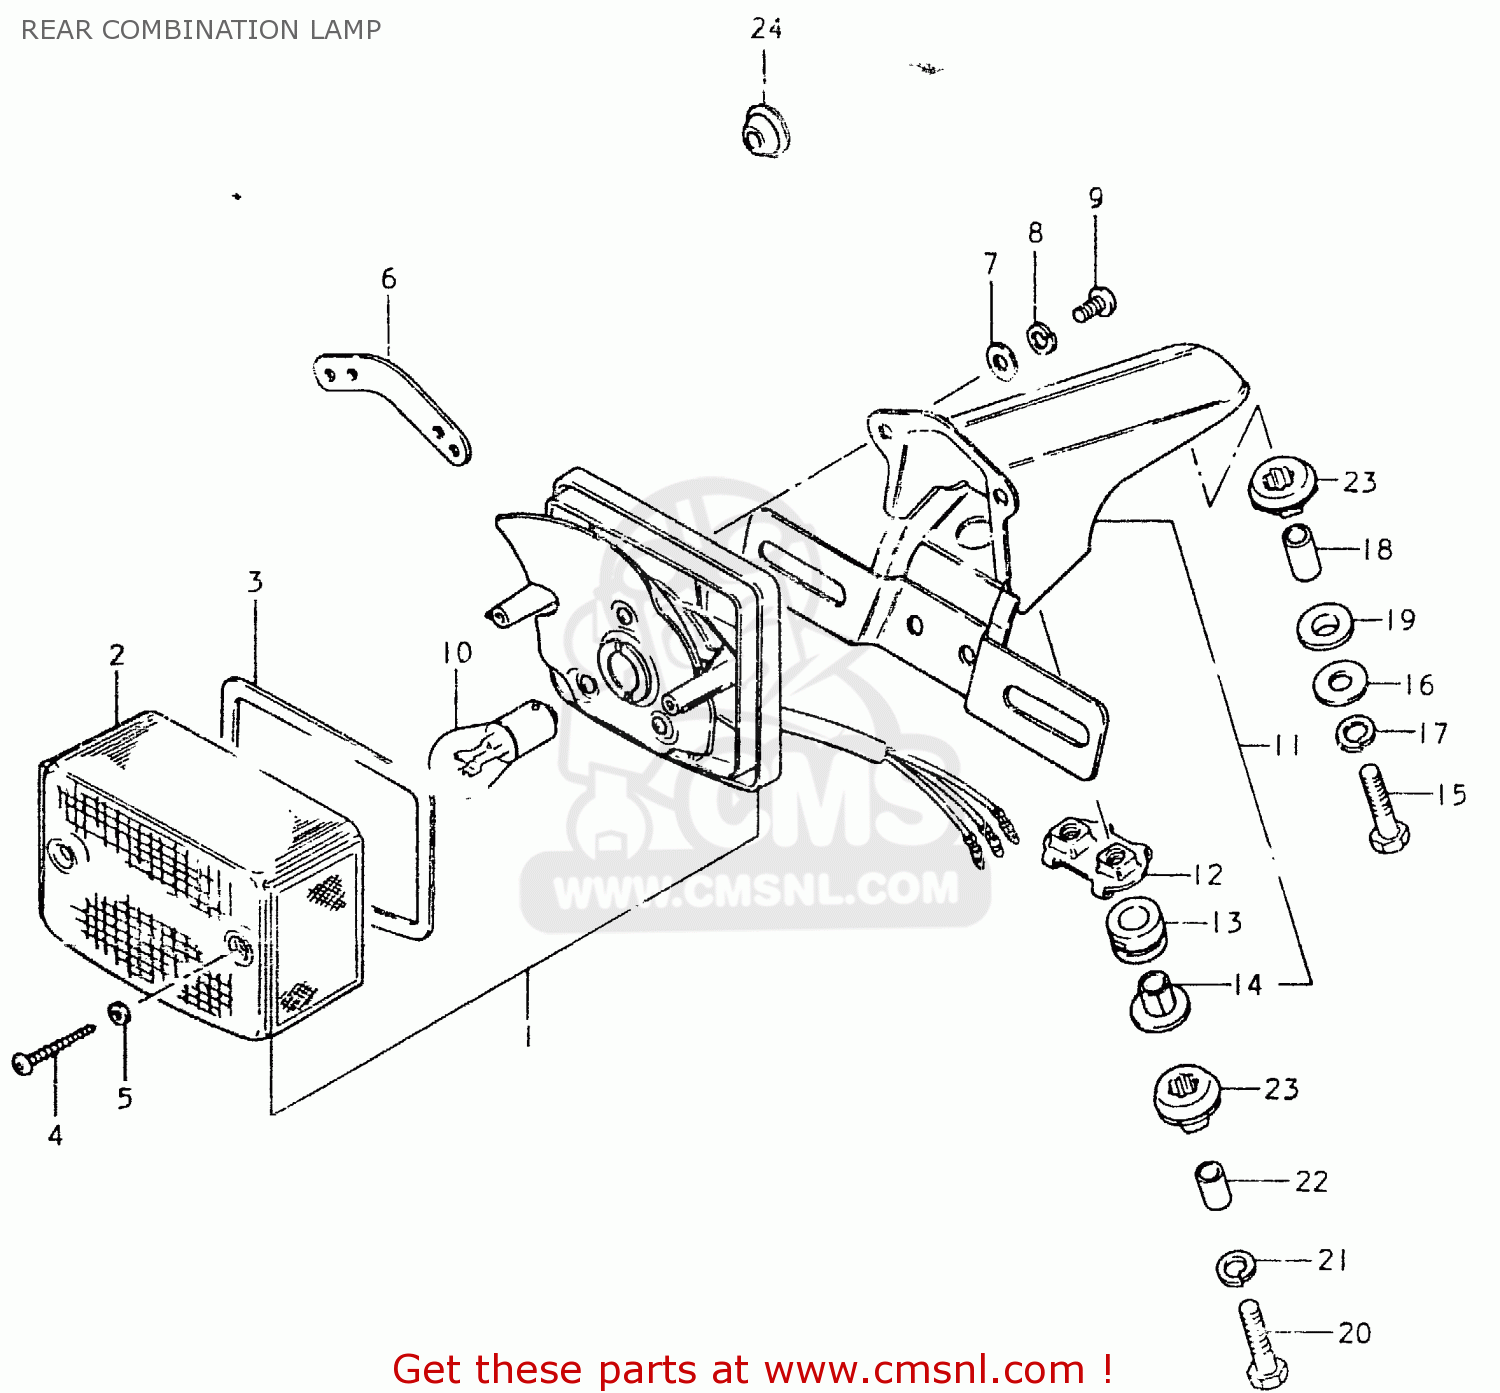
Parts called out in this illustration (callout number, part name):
1	LAMP UNIT,REAR COMBINATION
2	LENS
3	GASKET (NAS)
4	SCREW
5	GASKET (NAS)
6	PLATE,REAR COMBINATION LAMP
7	WASHER
8	LOCK WASHER
9	SCREW
10	BULB(6V10/3W,STANLEY,A4854H)
11	BRACKET UNIT,TAIL LAMP
12	PLATE
13	CUSHION
14	SPACER
15	BOLT
16	WASHER (6.5X20X1.2)
17	LOCK WASHER
18	SPACER
19	CUSHION
20	BOLT 6X40
21	LOCK WASHER
22	SPACER (6.8X10X11.5)
23	CUSHION
24	GROMMET
